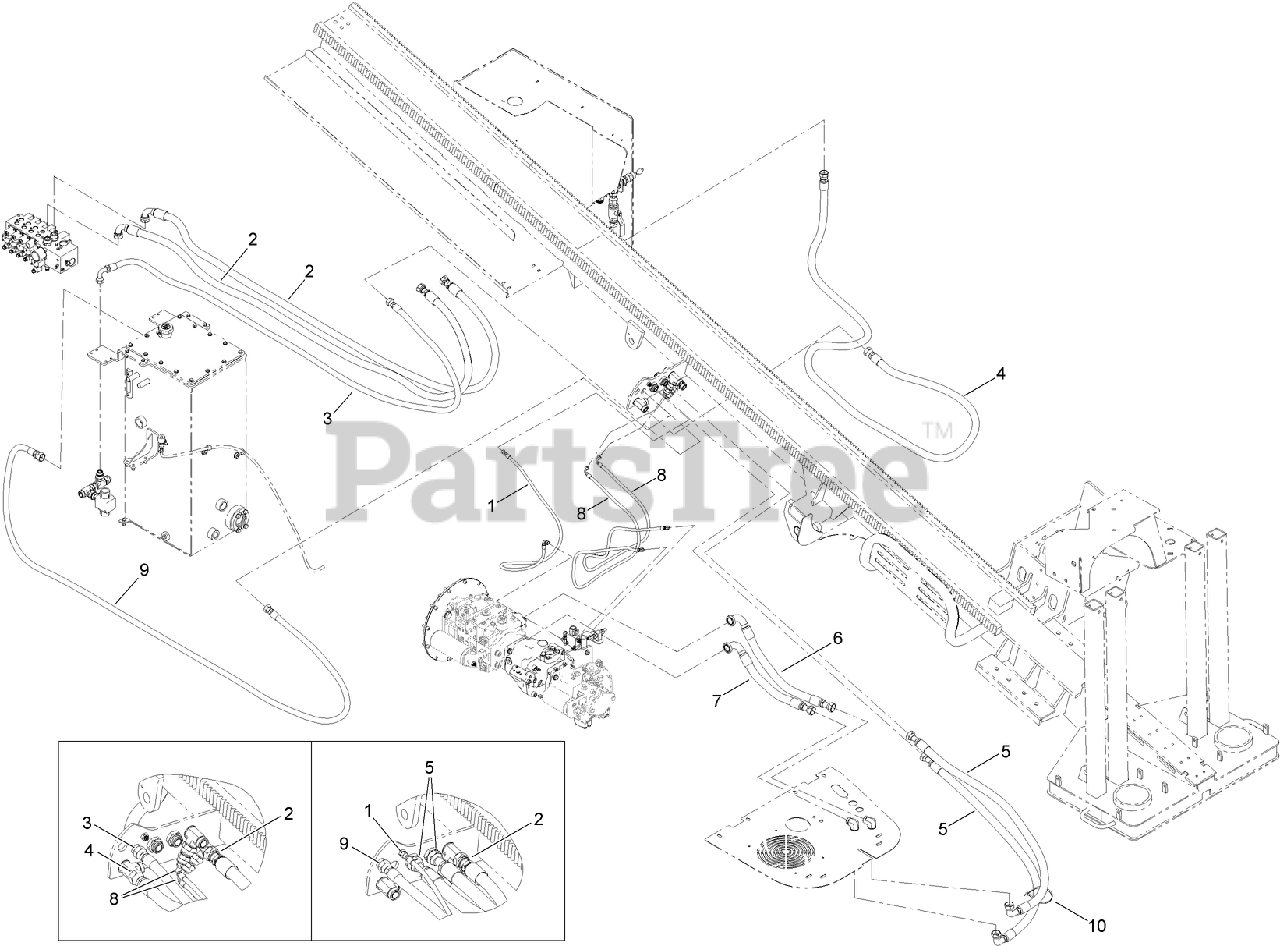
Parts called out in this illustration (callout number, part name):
1	HOSE ASM-HYD
2	HOSE ASM-HYD
3	HOSE ASM-HYD
4	HOSE ASM-HYD
5	HOSE ASM-HYD
6	HOSE ASM-HYD
7	HOSE ASM-HYD
8	HOSE ASM-HYD
9	HOSE ASM-HYD
10	TIE-CABLE
